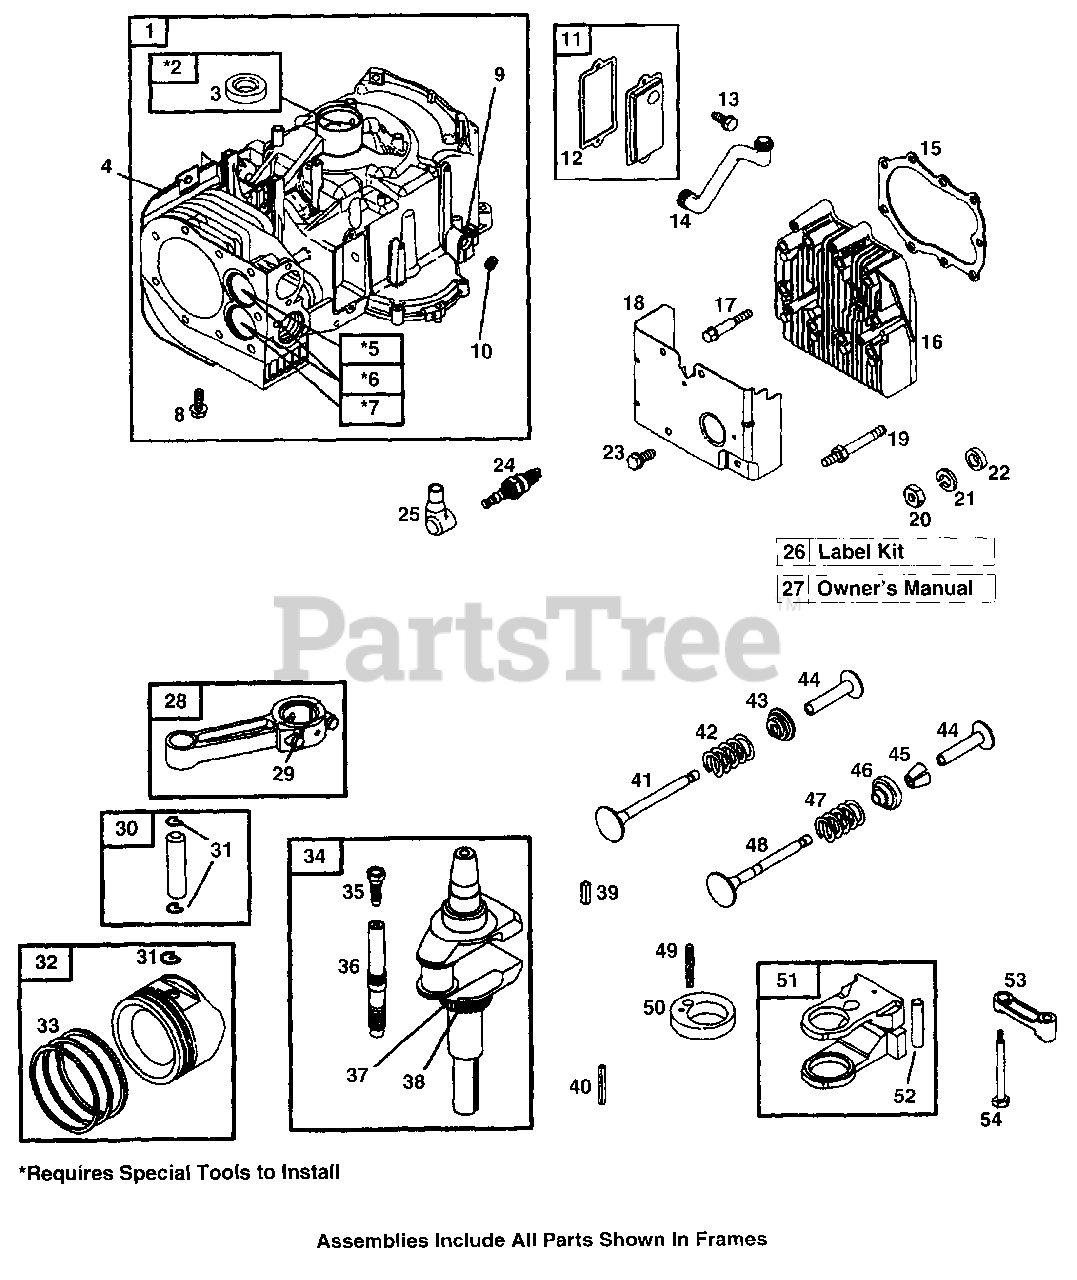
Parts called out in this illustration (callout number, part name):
1	Cylinder Assembly
2	Bushing/Seal Kit
3	Oil Seal
4	Cylinder Shield
5	Intake Valve Seat
6	Guide Bushing
7	Exhaust Valve Seat
8	Tapping Hex Screw
9	Governor Crank Bushing, 1/4" ID
10	Governor Arm Seal
11	Breather Assembly
12	Valve Cover Gasket
13	Screw
14	Breather Tube
15	Cylinder Head Gasket
16	Cylinder Head
17	Machine Hex Screw, 3" Long
18	Cylinder Head Cover
19	Hex Washer Head Stud, 3 15/16" Long
21	Lock Washer
23	Hex Screw
24	Resistor Spark Plug
25	Spark Plug Elbow
27	Owner's Manual
28	Connecting Rod, Std
29	Hex Screw
30	Piston Pin, Std
31	Piston Pin Lock
32	Piston / Ring Kit, Std
33	Ring Set, Std Chr
34	Crankshaft
35	Shoulder Screw
36	Crankshaft Extension
37	Timing Gear
38	Woodruff Key
39	Flywheel Key
40	Pulley key, 1/4"
41	Intake Valve
42	Valve Spring
43	Spring Retainer (Valves w/Groove Stem)
44	Valve Tappet
45	Valve Keeper
46	Rotocoil Assy, Exhaust Valve
47	Exhaust Valve Spring
48	Exhaust Valve
49	Groove Pin
51	Counterweight Assy
52	Counterweight Pin
53	Counterweight Link
54	Hex Screw
